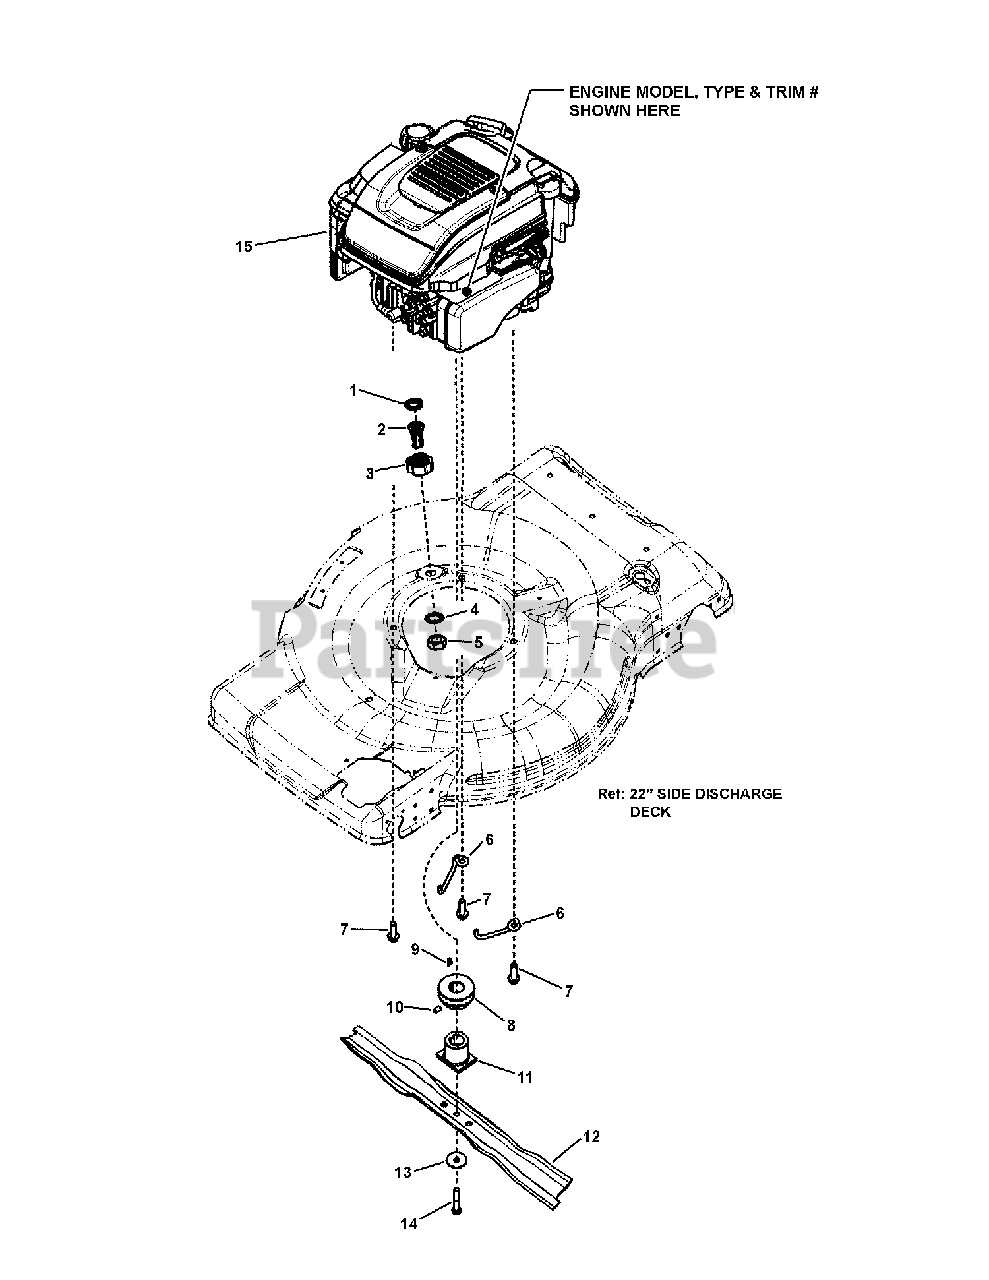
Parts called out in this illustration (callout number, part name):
1	WASHER, Hose
2	ADAPTOR, Washout Port, WBM
3	COUPLING, Hose
4	WASHER, 5/8" Internal Tooth Lock
5	NUT, 5/8-11 NC-2B Hex Jam
6	BELT GUIDE, Engine, Front Wheel Drive
7	SCREW, 3/8-16 X 1-1/4" Hex Washer Self-Tap
8	PULLEY, Engine PM, WBM
9	KEY, #HP-506 Hi-Pro
10	SET SCREW 5/16-18 x 1/2 Hex Recess
11	BLADE HUB
12	BLADE, Wave, Steel Deck
13	WASHER, Cone 13/32 x 1-13/32" Dia.
14	SCREW, 3/8-24 x 2" Hex Head Cap, GR 5
15	* ENGINE, B&S, 725 Series, X-Spec
